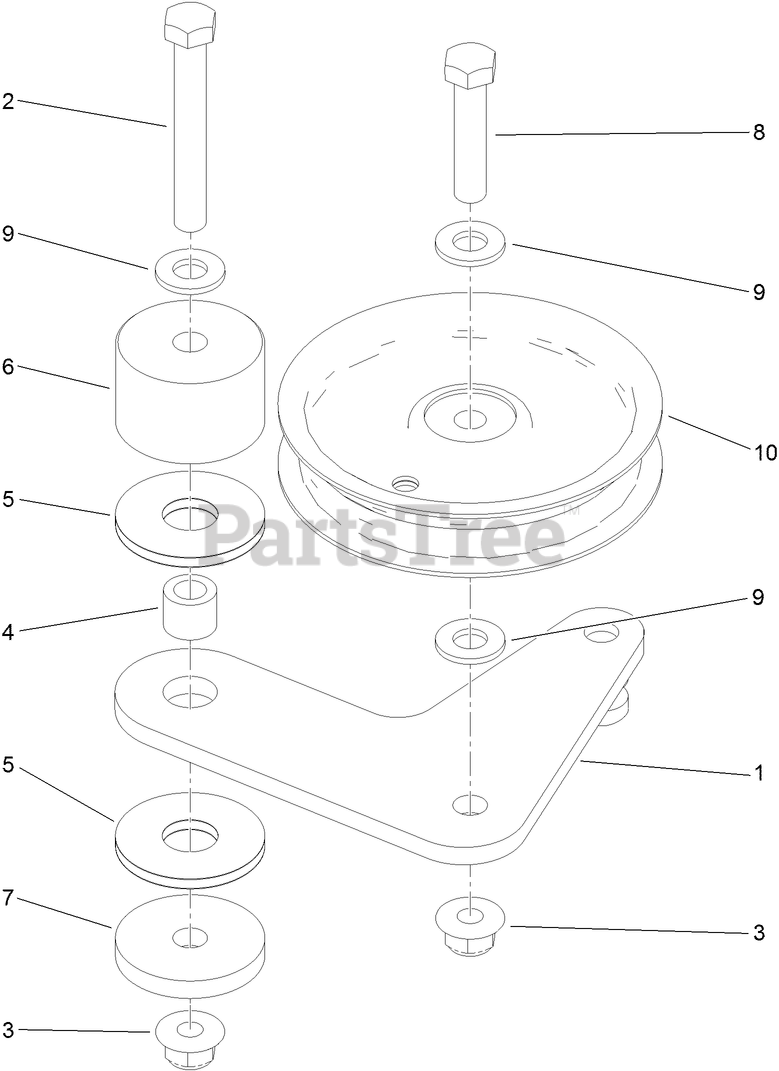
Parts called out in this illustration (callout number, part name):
1	PLATE-IDLER
2	SCREW-HH
3	NUT-HF, NI
4	BUSHING-LEVER, LIFT
5	WASHER-FRICTION, COMPOSITE
6	HUB-IDLER
7	WASHER-PLAIN
8	SCREW-HH
9	WASHER-FLAT
10	PULLEY-IDLER
